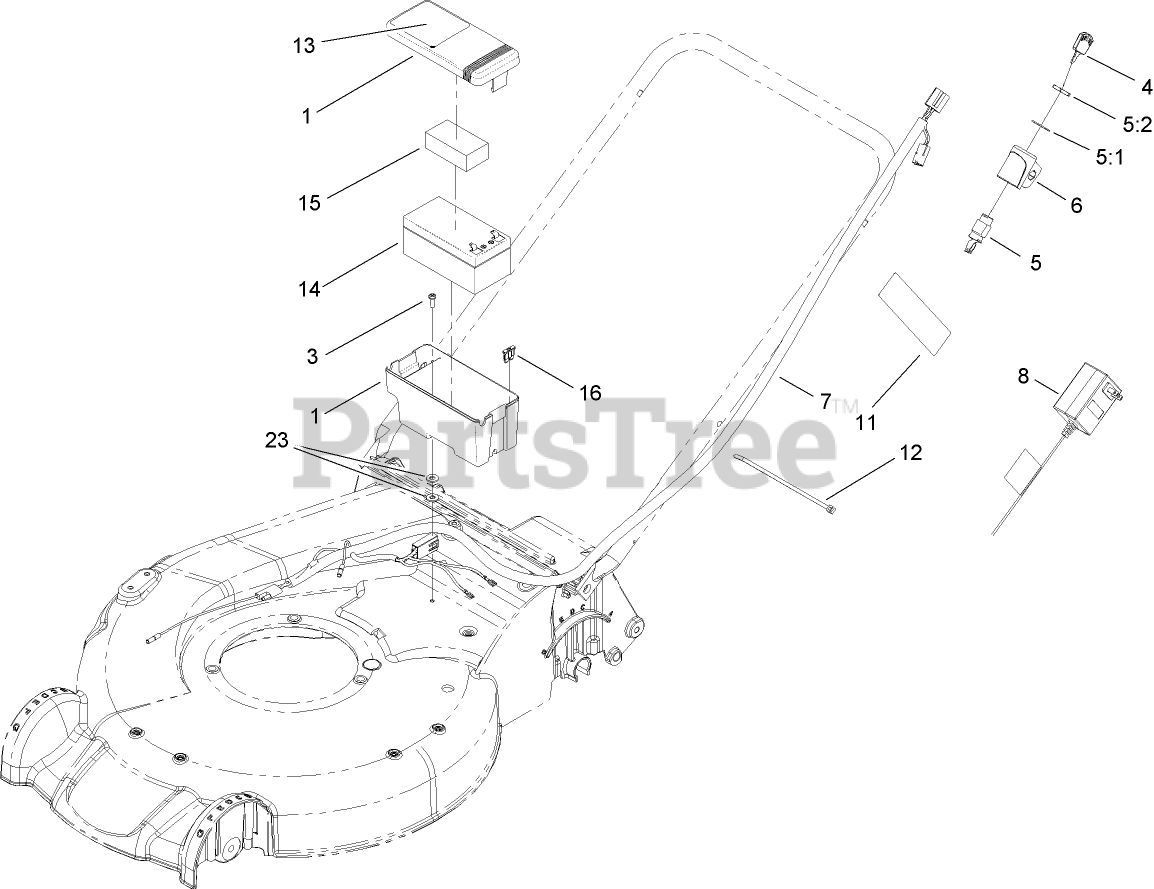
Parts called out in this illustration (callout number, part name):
1	BATTERY BOX ASM
5	STARTER SWITCH ASM
5:1	WASHER-LOCK
5:2	NUT-HH
6	MOUNT-SWITCH
7	HARNESS-WIRE
11	DECAL-WARNING
12	TIE-CABLE
13	DECAL-INSTRUCTIONAL
14	BATTERY-WET
15	FOAM-BATTERY, TOP
16	FUSE-40 AMP
23	WASHER-FLAT
